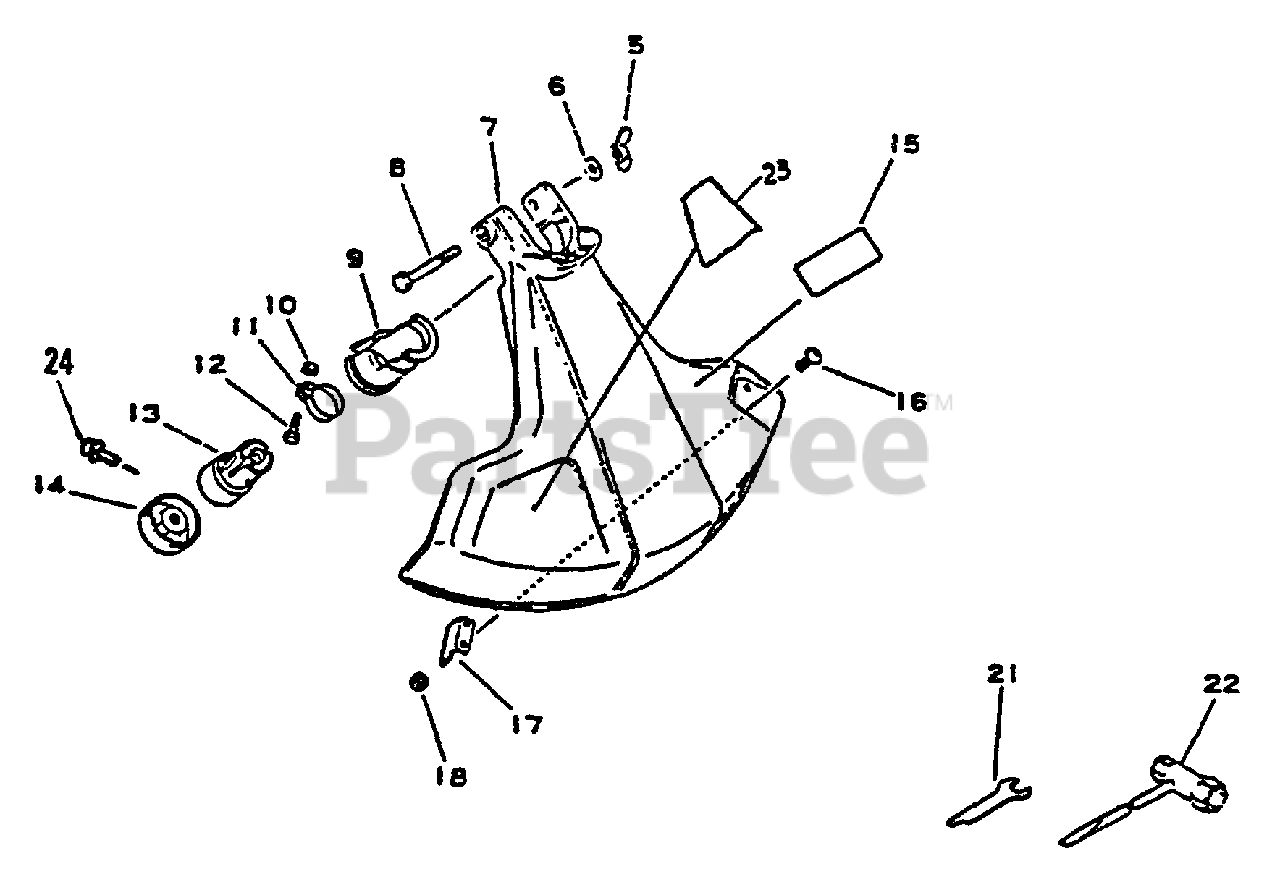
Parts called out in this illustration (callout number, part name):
5	WINGNUT - 6
6	WASHER - 6
7	SHIELD, DEBRIS - PLASTIC
8	BOLT - 6X50
9	BRACKET, BEARING CASE
13	GEAR CASE ASSY
14	ADAPTOR, BLADE - UPPER
15	LABEL - ECHO
16	SCREW - 5X16
17	KNIFE, TRIMMER LINE
21	SPANNER - 10mm
22	T-WRENCH - 8X19mm
23	LABEL - CAUTION
24	SCREW - 4X10
